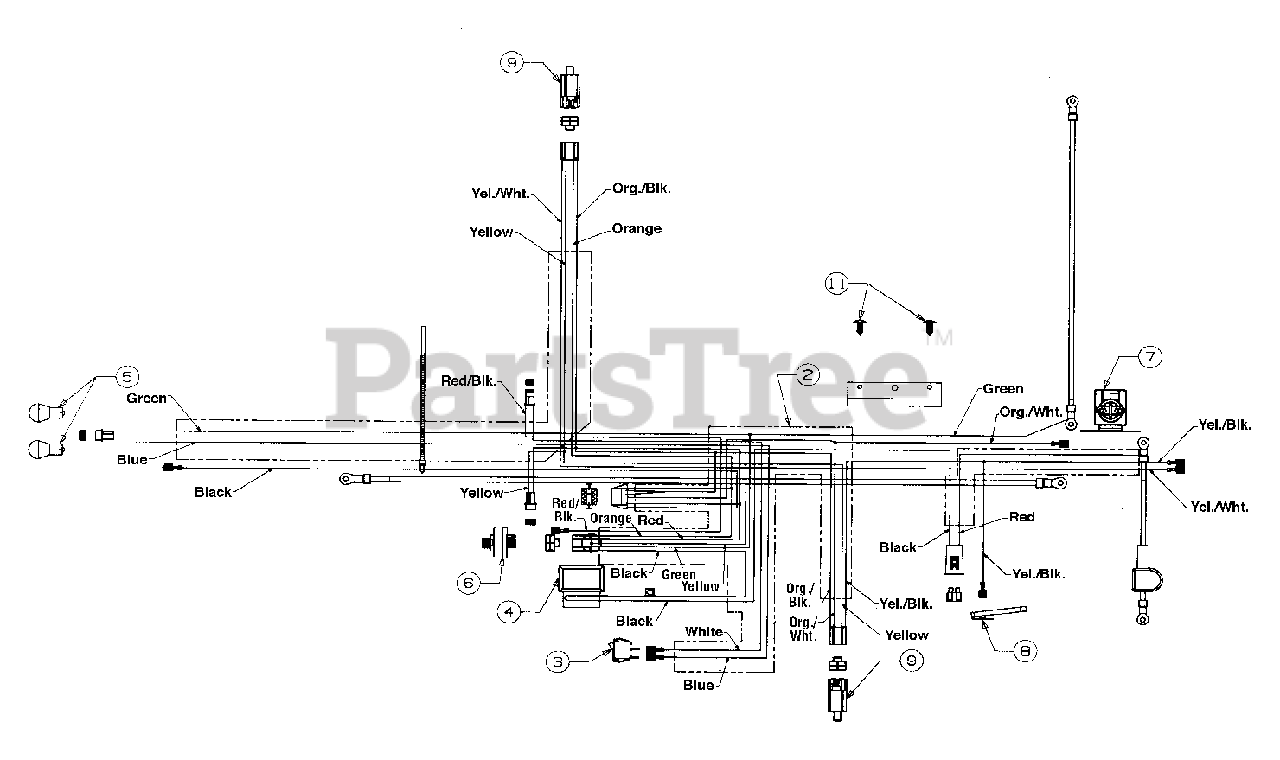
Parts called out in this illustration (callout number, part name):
2	Light Switch
3	Ammeter
4	Bulb
5	Ignition Switch
6	Solenoid
7	Safety Switch (Reverse)
8	Safety Switch
